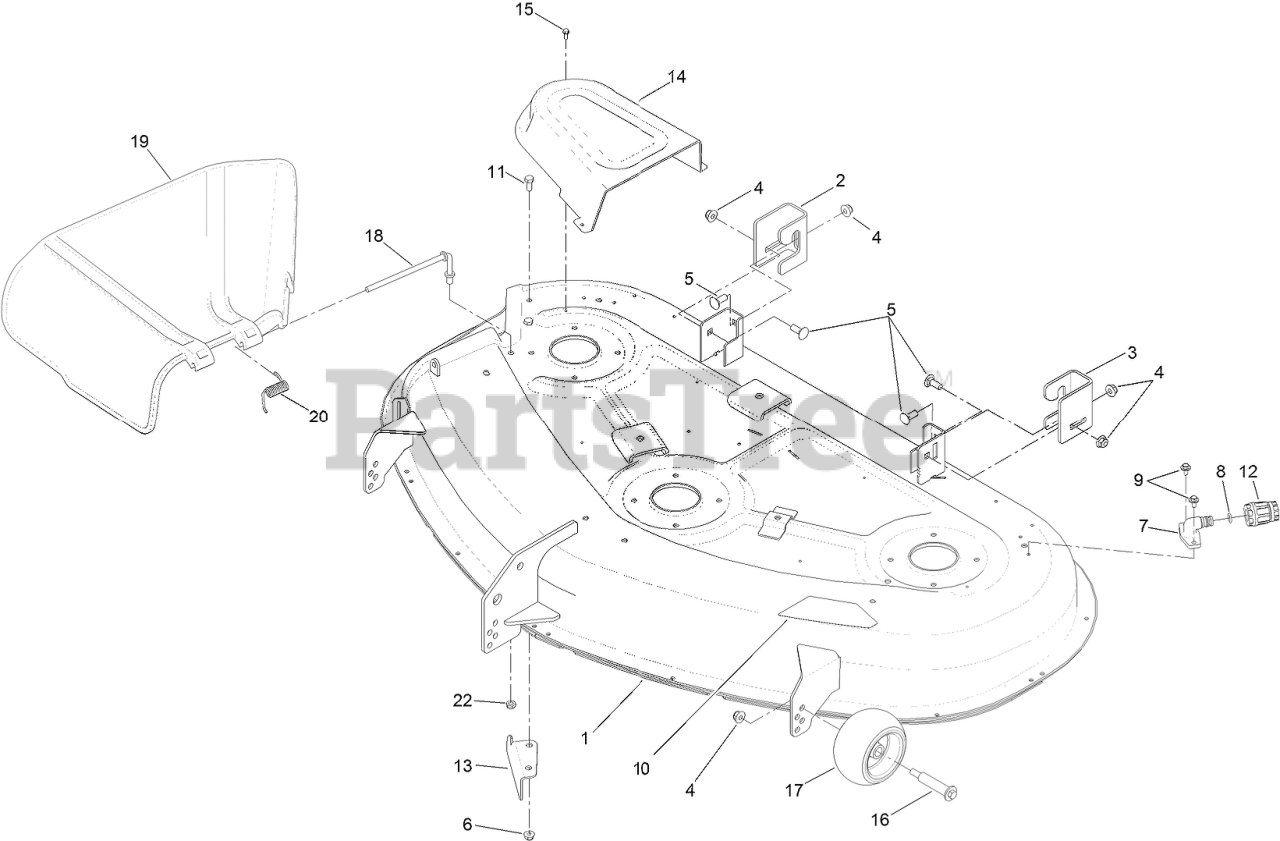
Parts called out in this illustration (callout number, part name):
1	50 INCH DECK AND DECAL ASM
2	BRACKET-HANGER, RH
3	BRACKET-HANGER, LH
4	NUT-HF, NI
5	BOLT-CARR
6	NUT-HF, NI
7	FITTING-WASHOUT
8	O-RING
9	SCREW-HHFTF
11	SCREW-HH
12	CONNECTOR-HOSE
13	BAFFLE-CUTOFF
14	COVER-BELT
15	SCREW-TAPTITE
16	BOLT-SHOULDER
17	ROLLER-SCALP, ANTI
18	ROD-PIVOT
19	DEFLECTOR
20	SPRING-TORSION
22	NUT-LOCK, NI
